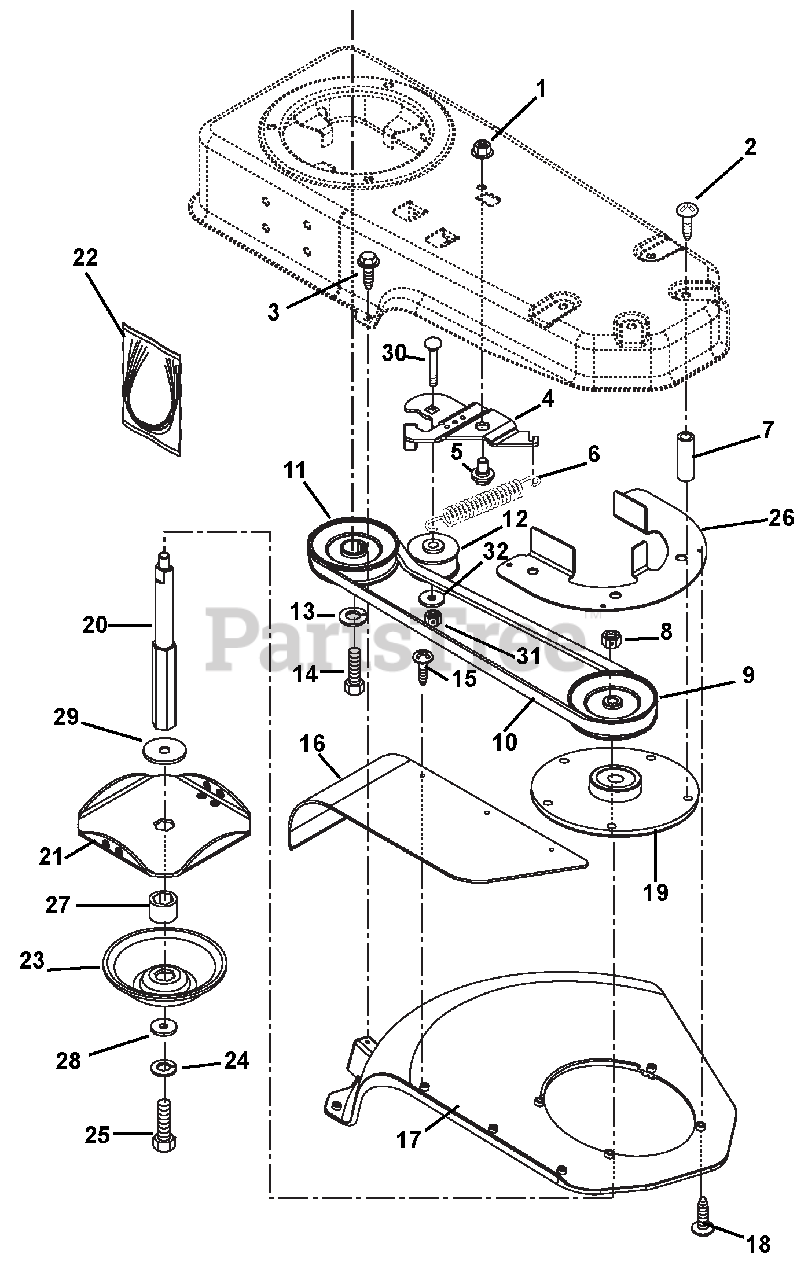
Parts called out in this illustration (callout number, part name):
1	NUT-LK-CTR-FLG .38-16 YWZC
2	@SCR-TAP.375-16X2.75 HWH TR YZ
3	SCR-TAP 10-24X.75 HWH TR YWZC
4	BRACKET - IDLER
5	BOLT-SHLDR .375-16X.150
6	SG-TENS .035X.45X2.75 WLD 3.5
7	BSHG-SPCR .406X.625X1.90
8	NUT-LK-FLG .375-24 GR5 YWZC
9	PLY-V 3.50 OD X .87 WIDE (CUT)
10	V-BELT, HA-RAW EDGE
11	SHEAVE-ENGINE 3.50 ODX.87 WIDE
12	IDLER - FLAT 1.875OD X .75WIDE
13	@WSHR-LK .38X.094 REG YWZC
14	BLT-HEX .38-24X1.0 YWZC GR5
15	SCR-TAP #10-16 X .625 HWH
16	GUARD - DEBRIS
17	SHIELD - TRIMMER
18	SCR-TAP 10-24X.75 HWH TR YWZC
19	HOUSING, JACKSHAFT -CHAMFERED
20	SHAFT - CUTTER - HEX
21	CUTTER - DISK
22	LINE - CUTTER 18" LG PKG OF 6
23	GUIDE - HEIGHT - HEX
23	GUIDE - HEIGHT - LONG LIFE
24	@WSHR-LK .31X.078 REG YWZC
25	@BLT-HEX .31-18X.75 GR5 YWZC
26	FINGER - BELT
27	SPACER - HEX
28	WSHR-FL-STL .344X1.125X.135
29	SHIELD - DUST
30	@BLT-RHDSSQNK .38-16X1.50 G5YZ
31	@NUT-LK-CTR .38-16 YWZC
32	@WSHR-FL-STL.406X.812X.065 YWZ
